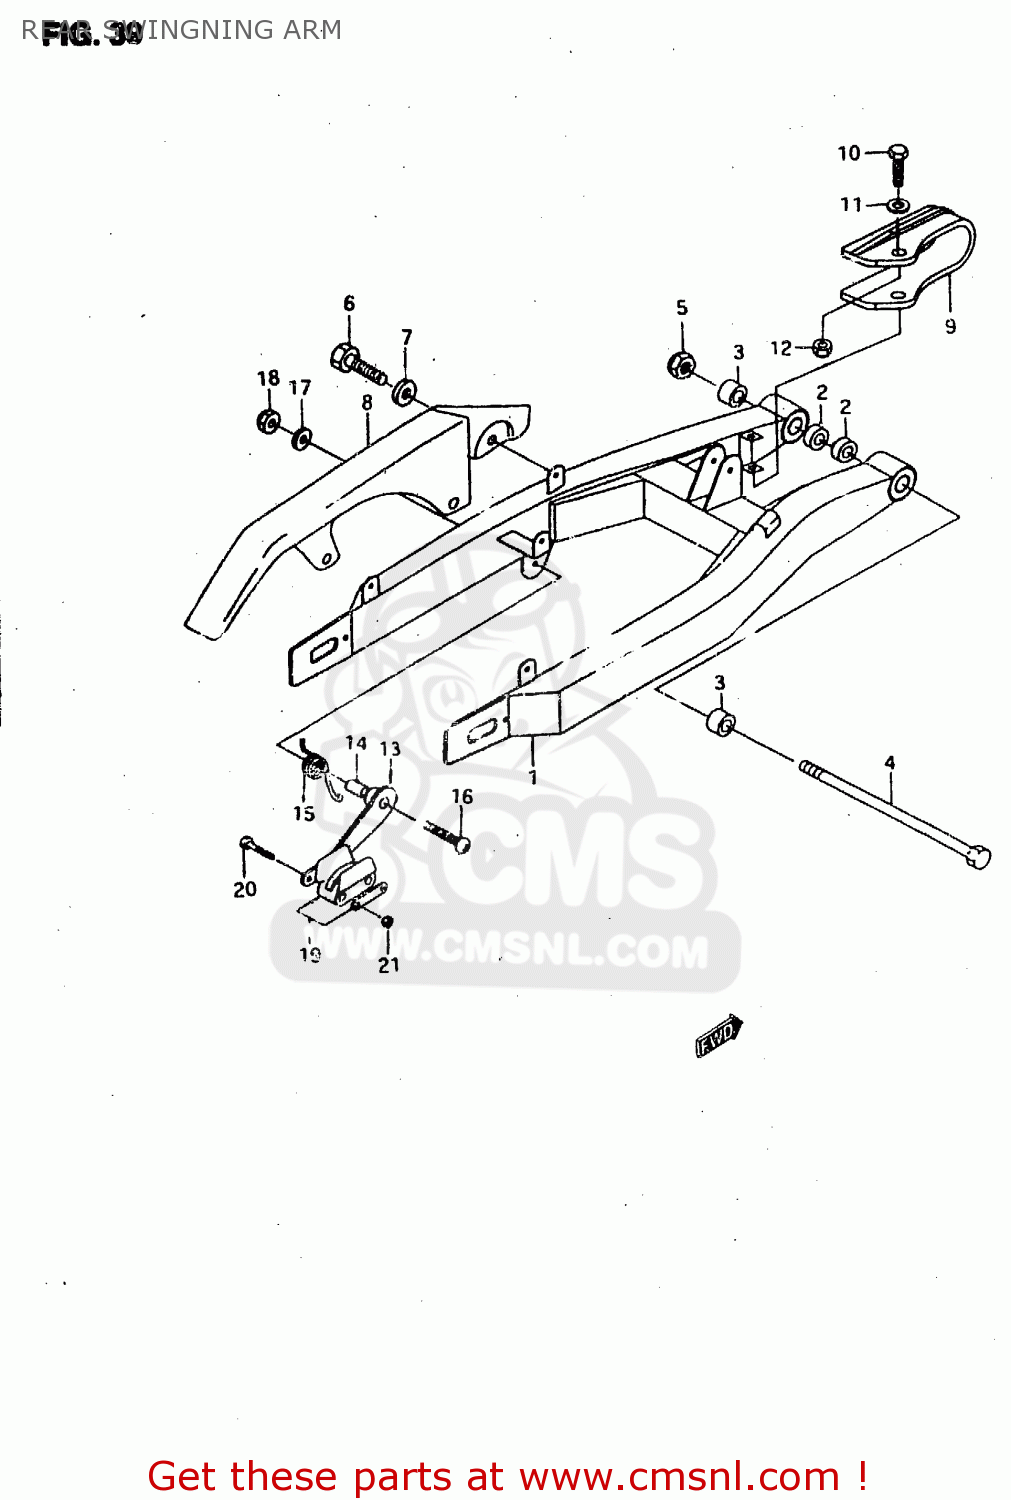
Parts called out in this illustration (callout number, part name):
1	SWINGING ARM ASSY, REAR
2	SPACER
3	FLEXIBLOC
4	SHAFT, SWINGING ARM PIVOT1
5	NUT
6	BOLT
7	WASHER(6.5X18X1.6)
8	CASE,CHAIN
9	BUFFER, CHAIN TOUCH DEFENSE
10	BOLT
11	WASHER
12	NUT
13	GUIDE,CHAIN
14	SPACER
15	GUIDE,CHAIN
16	SCREW 6X30
17	WASHER
18	NUT
19	ROLLER, CHAIN
20	SCREW
21	NUT
